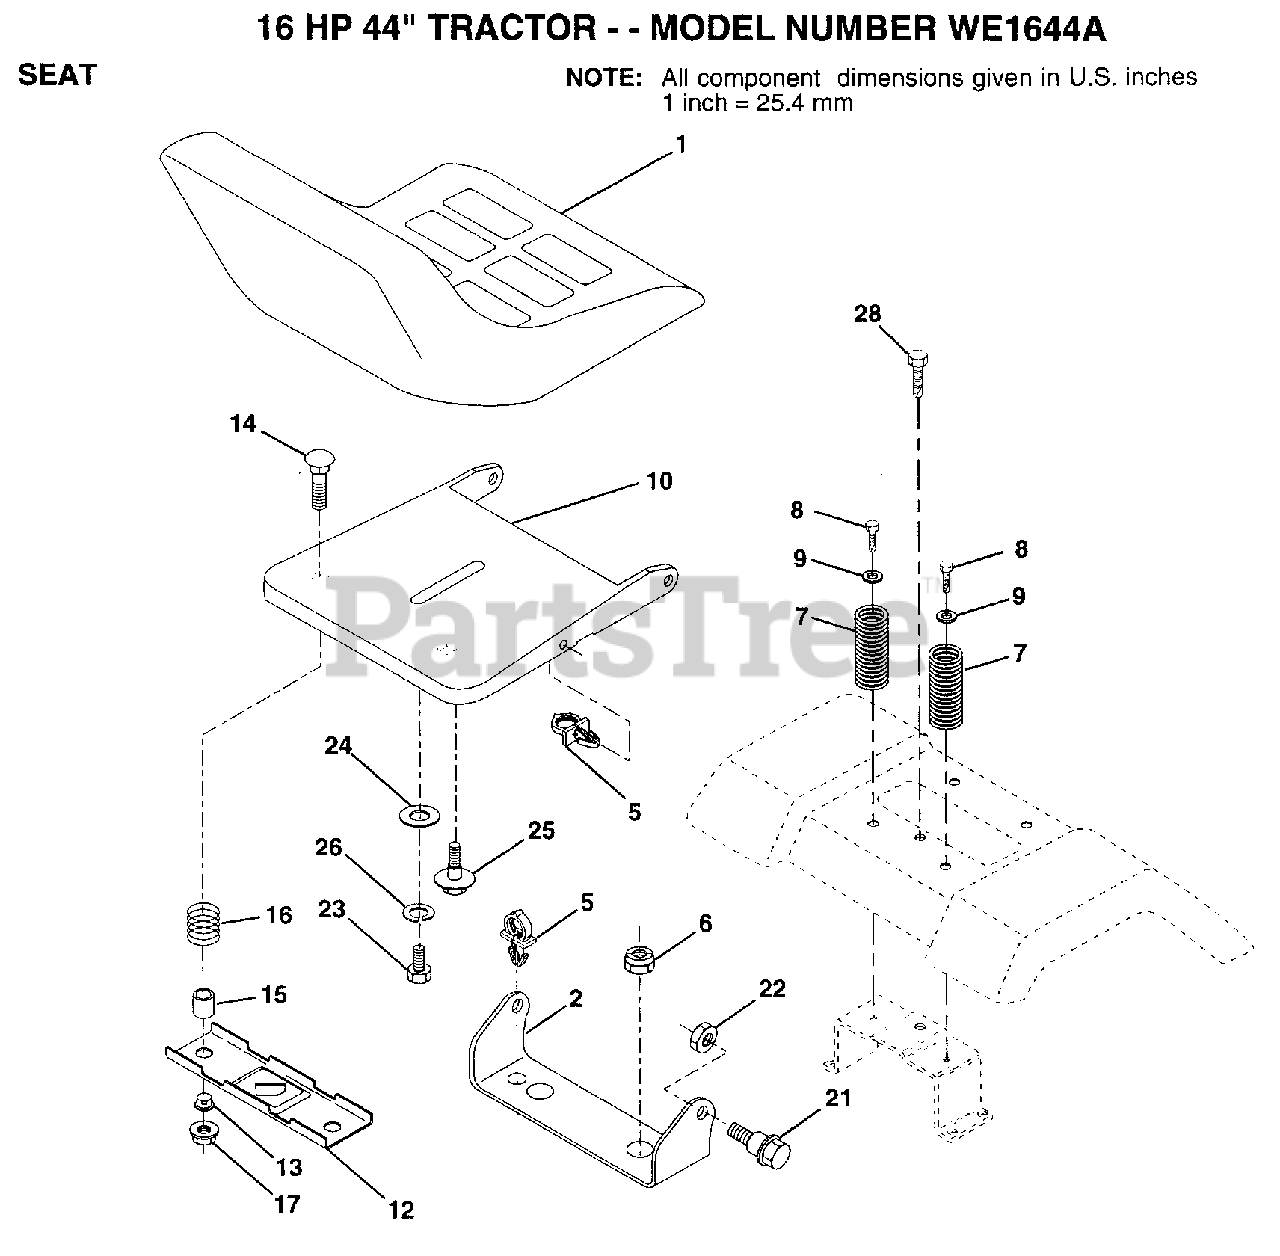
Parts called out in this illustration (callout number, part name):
2	BRACKET PVT SEAT
5	CLIP PUSH - IN
7	SPRING COMPRESSIO
8	SCREW LT
9	WASHER
12	BRKT SWITCH
13	BUSHING
15	SPACER SPLIT
16	SPRING COMPRESSED
21	BOLT.SHLD.5/16-18
23	BOLT
24	WASHER
25	"BOLT,SHOULDER"
26	LOCKWASHER
28	SCREW LT
